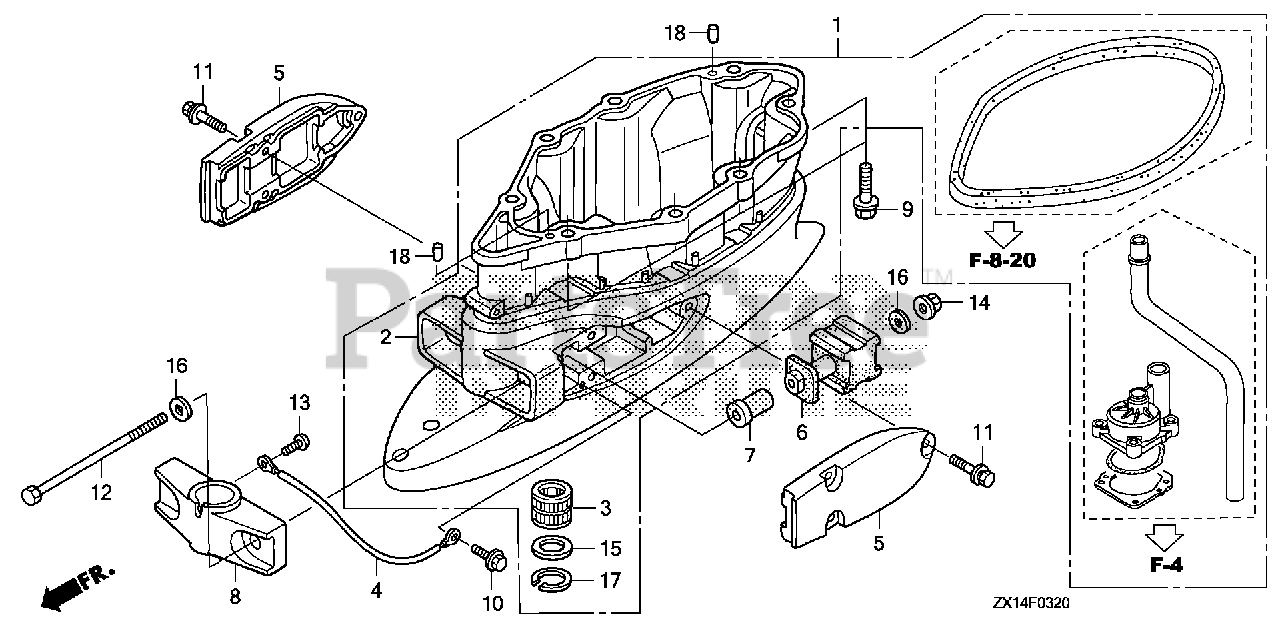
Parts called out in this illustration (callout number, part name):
1	CASE KIT, EXTENSION *NH282MU* (OYSTER SILVER METALLIC-U)
2	CASE, EXTENSION *NH282MU* (OYSTER SILVER METALLIC-U)
3	BUSH, VERTICAL SHAFT
4	WIRE, LEAD (1.5X137MM)
5	HOUSING, MOUNTING (LOWER) *NH282MU* (OYSTER SILVER METALLIC-U)
6	RUBBER, MOUNT (LOWER)
7	COLLAR, MOUNTING (LOWER)
8	HOUSING, CENTER MOUNTING (LOWER) *NH282MU* (OYSTER SILVER METALLIC-U)
9	BOLT, FLANGE (10X40)
10	BOLT, FLANGE (6X12)
11	BOLT-WASHER (8X30)
12	BOLT, HEX. (12X225)
13	SCREW, PAN (6X8)
14	NUT, FLANGE (12MM)
15	WASHER (26MM)
16	WASHER, PLAIN (12MM)
17	CIRCLIP (INNER) (40)
18	PIN, DOWEL (6X10)
